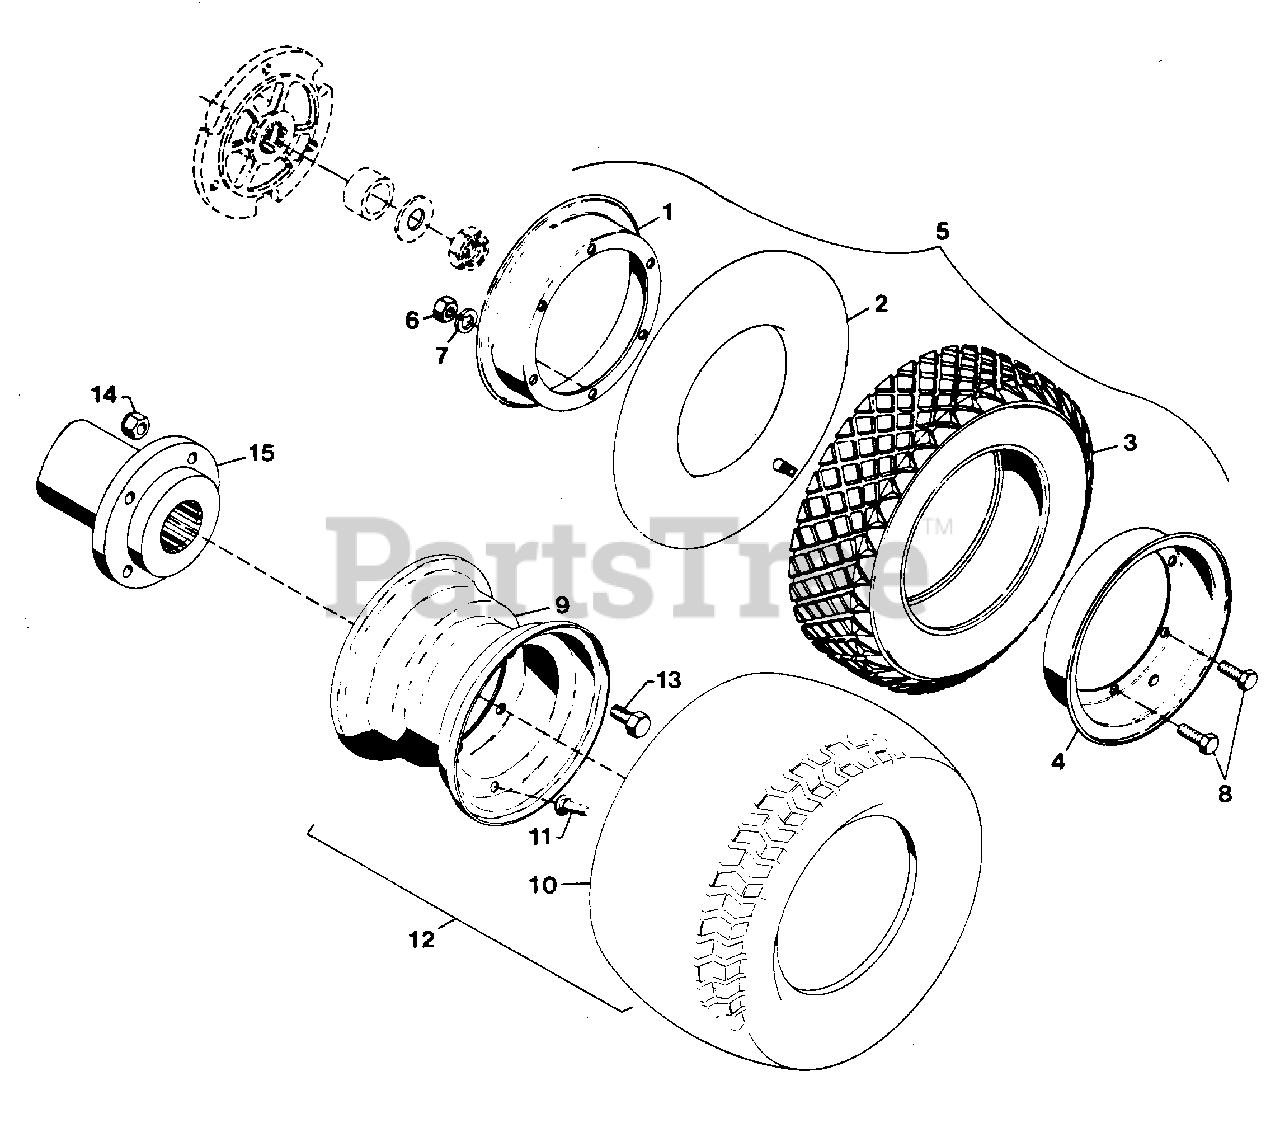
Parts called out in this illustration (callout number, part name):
1	DISC, INNER WHEEL
2	TUBE, 500X8
3	TIRE, TRACTOR DIAMOND TREAD 4.80X4.00-8
4	DISC, WHEEL
5	ASM., SUPER GRIP WHEEL 4.00-8
6	NUT, JAM 3/8-16 HEX
7	WASHER, LOCK 3/8 REG.
8	BOLT, HEX 3/8-16X.625
8	BOLT, HEX 3/8-16X.750
9	RIM, 18X8.50-8
10	TIRE, 18X8.50-8
11	ASSEMBLY, VALVE STEM
12	ASSEMBLY, WHEEL 18X8.50X8
13	BOLT, HEX 1/2-13X1.50
14	NUT, LOCK 1/2-13
15	HUB, FOR 18X8.50X8 WHEEL ASM.
